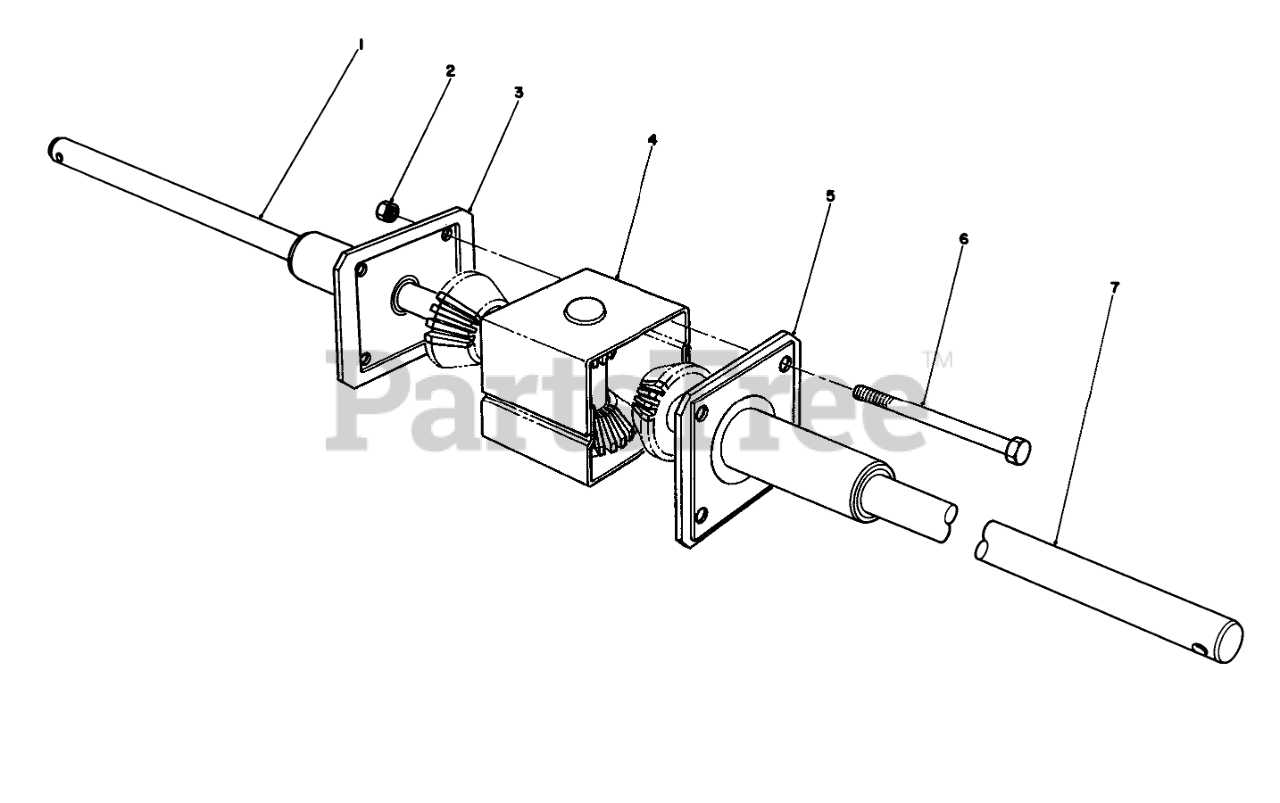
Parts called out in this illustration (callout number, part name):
2	NUT-LOCK, CONE
3	END CAP/BRG ASM
4	GEAR CASE ASM
5	END CAP &BEARING ASY
6	SCREW-HH
